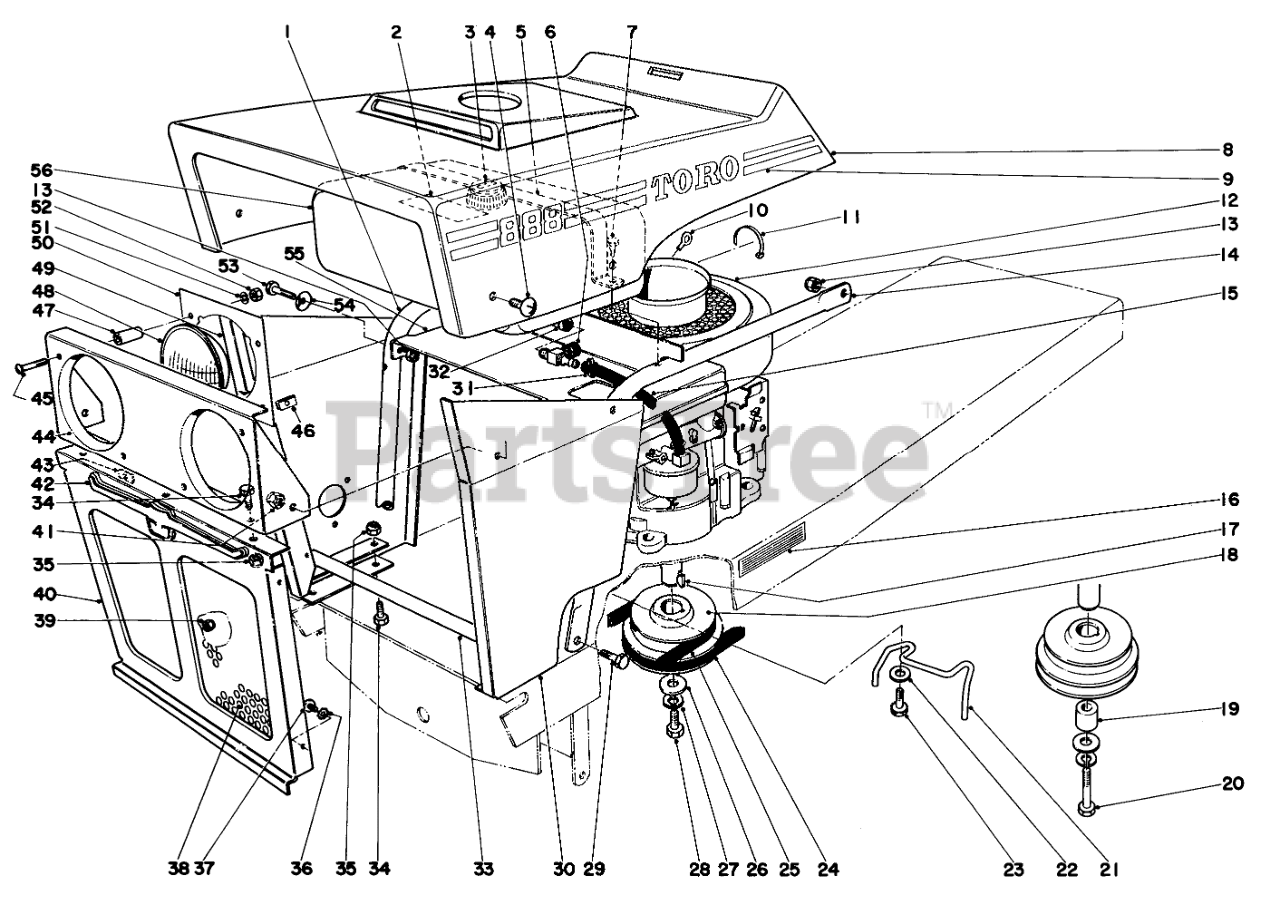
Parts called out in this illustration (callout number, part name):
1	Support-R.H.
2	Decal
3	Gas Cap
4	Round Head Screw
5	Hold Down Gas Tank
6	Shut Off Valve
7	SCREW-HWHTF
9	Decal Hood Left
11	Cable Tie
12	Engine
13	NUT-LOCK, CONE
14	Support Left
16	Decal
17	KEY-WOODRUFF
18	Pulley
19	Spacer
20	SCREW-HH
21	Belt Guide
22	WASHER-FLAT
23	1/4-20X5/8 THDG SEMS
24	Belt
25	V BELT PTO
26	WASHER-FLAT
27	WASHER-LOCK
28	SCREW-HH
29	SCREW-HH
30	Skin Left Front
31	Clamp
32	Elbow
33	Hinge
34	SCREW-HH
35	NUT-LOCK, CONE
36	WASHER-LOCK, EXT
37	10-24 X 3/8 PAN HD SC
38	Grille Panel
39	NUT-LOCK, NI
40	Grille
41	NUT-LOCK, CONE
42	Bullshead
43	Timmerman Nut
44	Headlamp Panel
46	NUT-CLIP,U
47	Spacer
48	HEAD LAMP
49	Skin Right Front
50	Headlight Holder
51	WASHER-LOCK/SP
52	NUT-HEX
53	SCREW-HH
54	WASHER
55	Tray Gas Tank
56	Gas Tank
